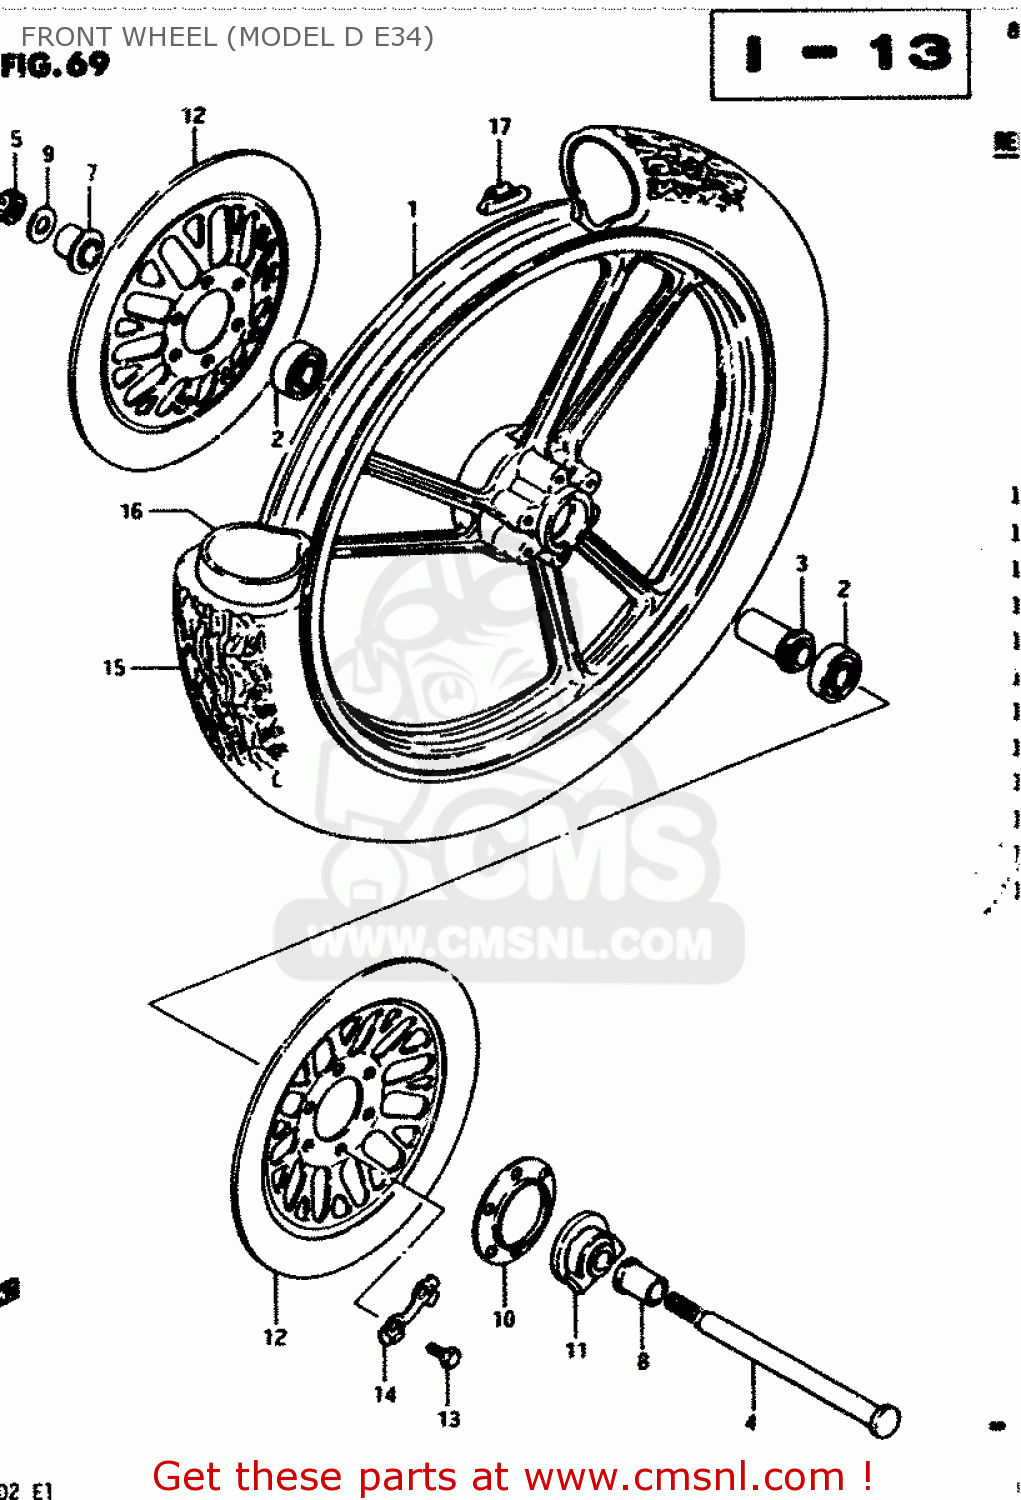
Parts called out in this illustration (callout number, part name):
1	WHEEL, FRONT (1.85X18)
2	BEARING
3	SPACER,FR HUB BEARING
4	AXLE,FRONT
5	NUT 12MM
6	COTTER PIN
7	SPACER,FR HUB BEARING,R
8	SPACER(15X22X30)
9	WASHER
10	DUST SEAL,SPEEDOMETER GEAR BOX
11	BOX ASSY,SPEEDOMETER GEAR
12	DISK, FRONT BRAKE
13	BOLT(8X25)
14	WASHER
15	TIRE,FRONT
16	TUBE,INNER
17	BALANCER,WHEEL
